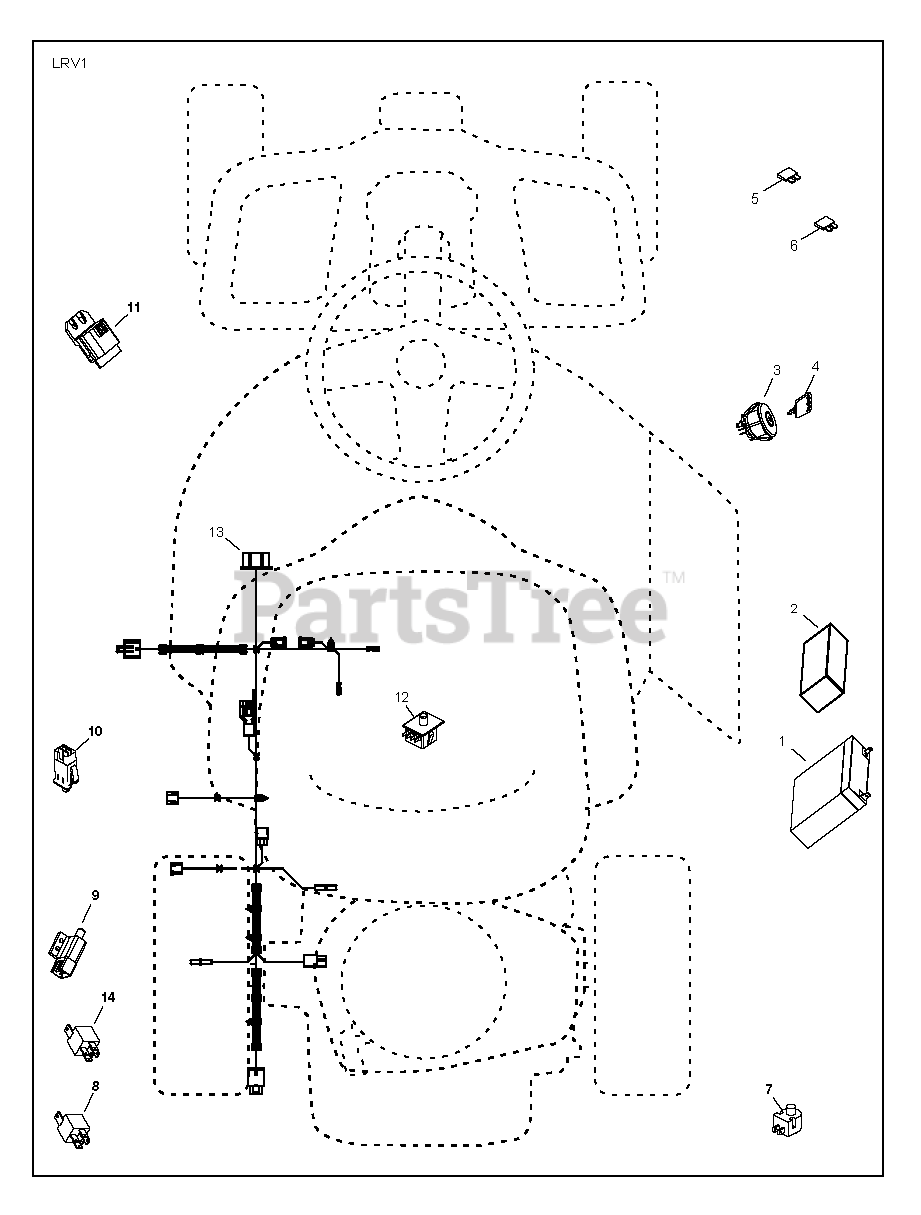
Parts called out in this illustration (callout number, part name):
1	RP BATTERY.2.8H.LRVA
2	FOAM.POLYURETHANE
3	SWITCH.IGN.DELTA.W.LGH.ROS
4	KEY.CHAIN.BLISTER.PACK.GEN.INT
5	FUSE
7	PLUNGER SWITCH (COLOR:OLIVE)
8	RELAY, 40A
9	SWITCH INTERLOCKT
10	SWITCH INTERLOOK PUSH-IN
11	MODULE.STARTING.RECOIL.LRV
12	SWITCH.SEAT.DP W/RAMPS
13	RP ARNESS,IGN,ELECTSTART,LRV
14	RELAY.ASSY.T
